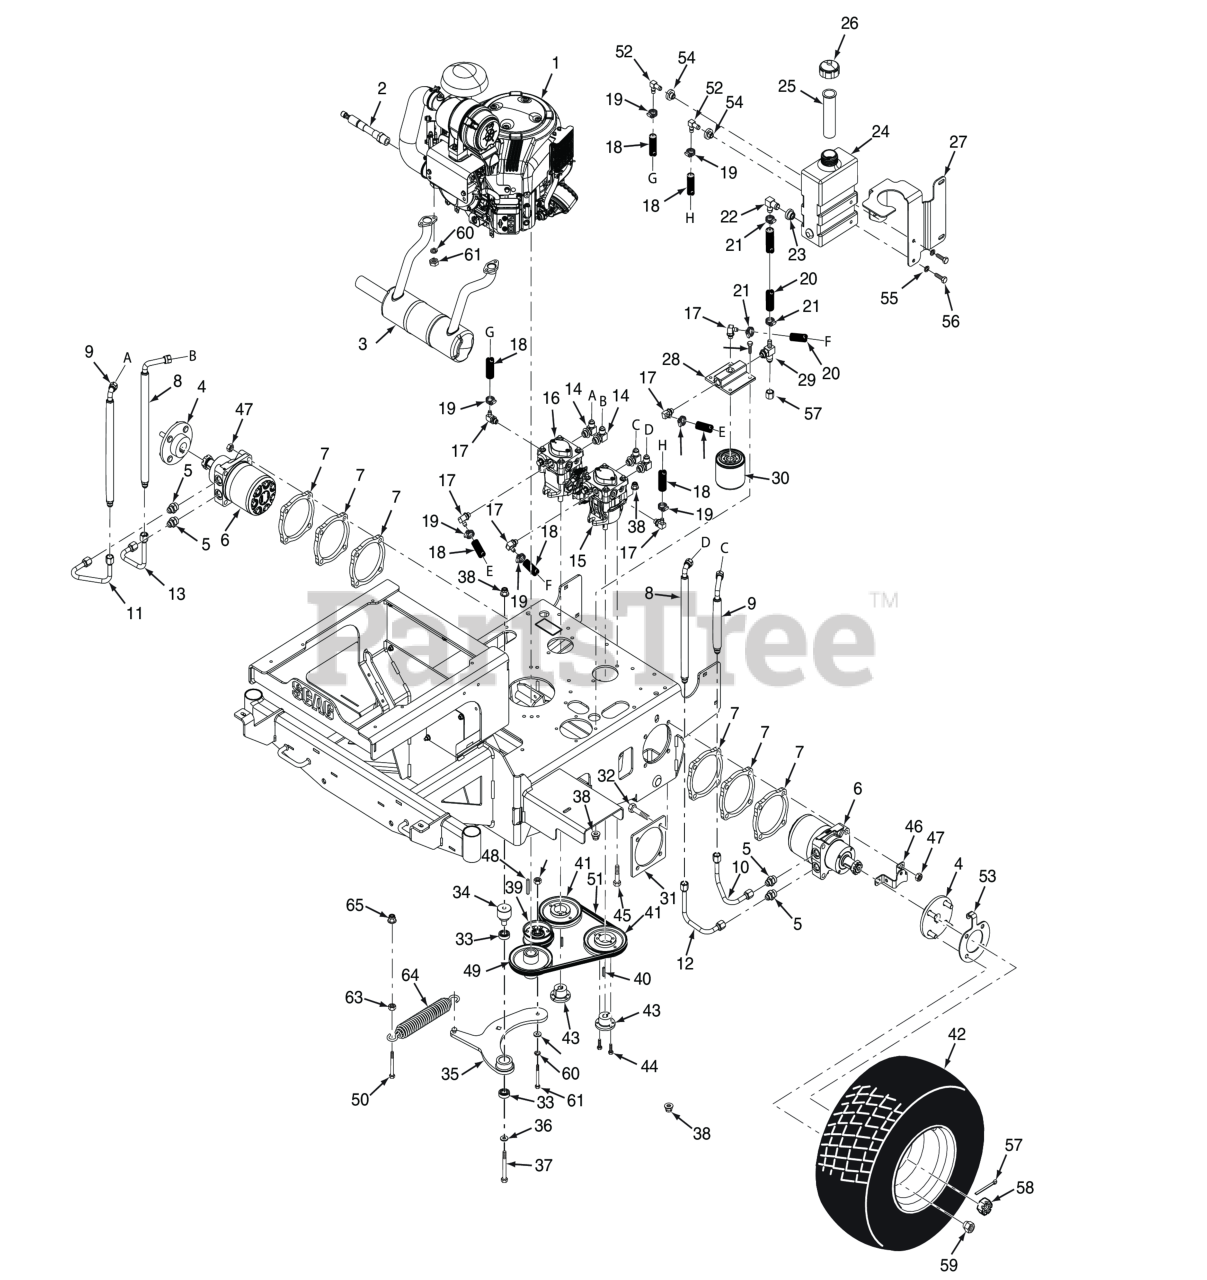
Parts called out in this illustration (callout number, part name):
1	Engine, 23 HP Briggs Vanguard
2	Hose, Oil Drain, Kohler - ECV860
3	Muffler, 21 HP BV
4	Wheel Hub Assy., SVRII
5	TUBE UNION, 3/4-16 JIC TO 7/8-14 "O" RING
6	Wheel Motor, Parker
7	Spacer, Wheel Motor
8	Hose Assy, 17.50"
9	Hose Assy, 16.25
10	Tube Assy, 1/2" LH Upper
11	Tube Assy, 1/2" RH Upper
12	Tube Assy, 1/2" LH Lower
13	Tube Assy, 1/2" RH Lower
14	Elbow, 90 Degree 3/4-16 JIC x 3/4-16 O-Ring
15	Pump, LH
16	Pump, RH
17	Elbow, 90 Degree - 9/16" O-Ring x 3/8" Hose
18	Hose, 3/8" ID - 10-1/4" Long (Order By The Inch)
19	Clamp, .69" Max. / .25" Min. Dia.
20	Hose Assembly, 1/2" ID (Oil Reservoir to Filter Base)
21	Clamp, Cable 3/4" I.D.
22	Fitting, 90 Degree - 1/2" Hose
23	Bushing, 0.78" Dia. Viton
24	Hyd. Tank Assy
25	Insert, Filler Neck
26	CAP, HYDRAULIC TANK
27	Mounting Bracket, Oil Reservoir
28	Filter Head Assembly
29	Tee, 3/8" O-Ring x JIC x 1/2" Hose
30	OIL FILTER, SPECIAL
31	Plate Weldment, Motor Backing
32	Bolt, Hex Head 1/2-13 x 4-1/4"
33	BEARINGS, BALL, NEUTRAL RETURN
34	Pivot, Idler
35	Idler Arm Assembly
36	Flatwasher, 3/8 (.391 x .938 x .105 HD) Grade 8
37	Bolt, Hex Head 3/8- 16 x 3.50 - Stainless Steel
38	Nut, Flange Elastic Stop 3/8 - 16 - Stainless Steel
39	Pulley, 3-1/2" Dia.
40	KEY, 5 MM X 5 MM X 25 MM
41	Pulley, 5.45 OD - Tapered Bore"
42	Wheel Assembly, 20 x 12 - 10
43	Hub, Tapered, 15mm Bore
44	Bolt, Hex Head 1/4-20 x 1" Grade 8 Black
45	Bolt, Hex Head 3/8 - 16 x 1.50 - Stainless Steel
46	Plate, Speed Sensor
47	Locknut, Hex 1/2-13 Center Lock
48	Key, 1/4 x 1/4 x 2.0"
49	Pulley 5.45 OD x 1.125 Bore
50	Bolt, Hex Head 3/8-16 x 2-1/4" - Stainless Steel
51	Belt, Pump Drive
52	Elbow, 90 Degree, 9/16-18 JIC x 9/16 O-Ring
53	Plate, Hub Magnet Holder
54	Bushing, 0.56" Dia. Viton
55	Bolt, Hex 5/16 - 18 x .75 - Stainless Steel
56	Washer, Lock 5/16 Spring - Stainless Steel
57	Pin, Cotter 9/16" x 1-1/2"
58	Nut, Hex Castle 1.0-20 UNEF
59	Wheel Nut, 1/2-20 x 13/16
60	Bolt, Hex Head 7/16-20 x 1.25"
61	Flatwasher, 7/16-.469 x 1.750 x 1/4"
62	Flatwasher, 7/16-.469 x 1.75 x .25 (48, 52)
63	Nut, 3/8 - 16 - Stainless Steel
64	Spring, PTO (Gasoline Engines)
65	Nut, Flange Elastic Stop 3/8 - 16 - Stainless Steel
